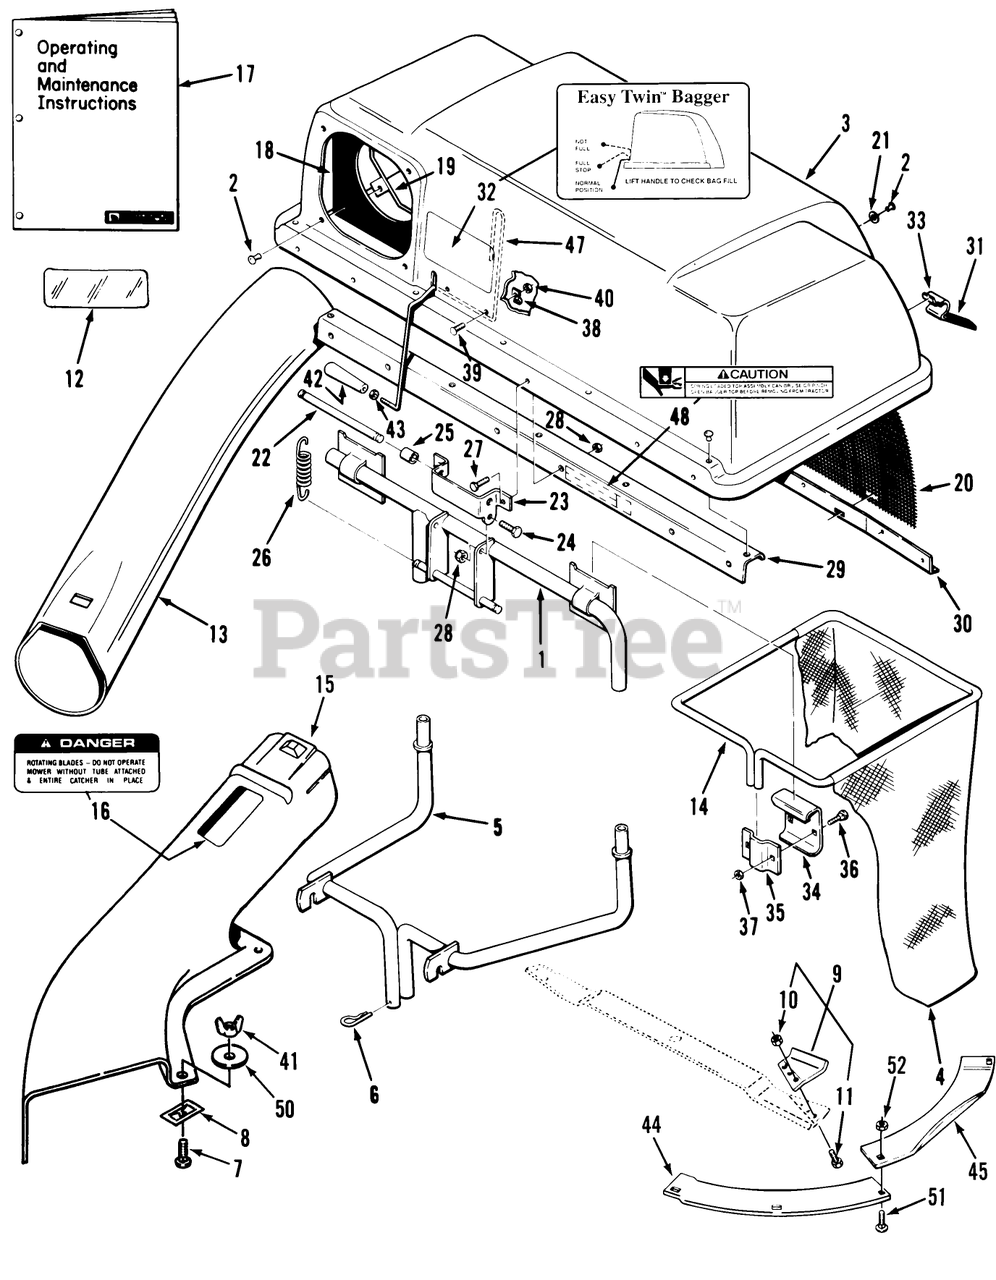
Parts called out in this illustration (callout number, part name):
2	RIVET-BLIND
5	ASM-QUICK ATTACH *B
6	Hairpin
8	SPEED NUT
9	S/A LIFT TAB KIT
10	BOLT 5/16-18X5/8
11	NUT-HEX
12	DECAL-OVERLAY
13	CHUTE-BAGGER (L)
16	DECAL-DANGER
17	Operating and Maintenance Instructions
19	CLAMP-SEAL
20	SCREEN-BAGGER
22	PIN-SPRING
26	SPRING-EXTENSION
42	HANDLE-TAPERED
45	PLATE MOWER *B
47	FEELER-FILL, BAG
50	WASHER
